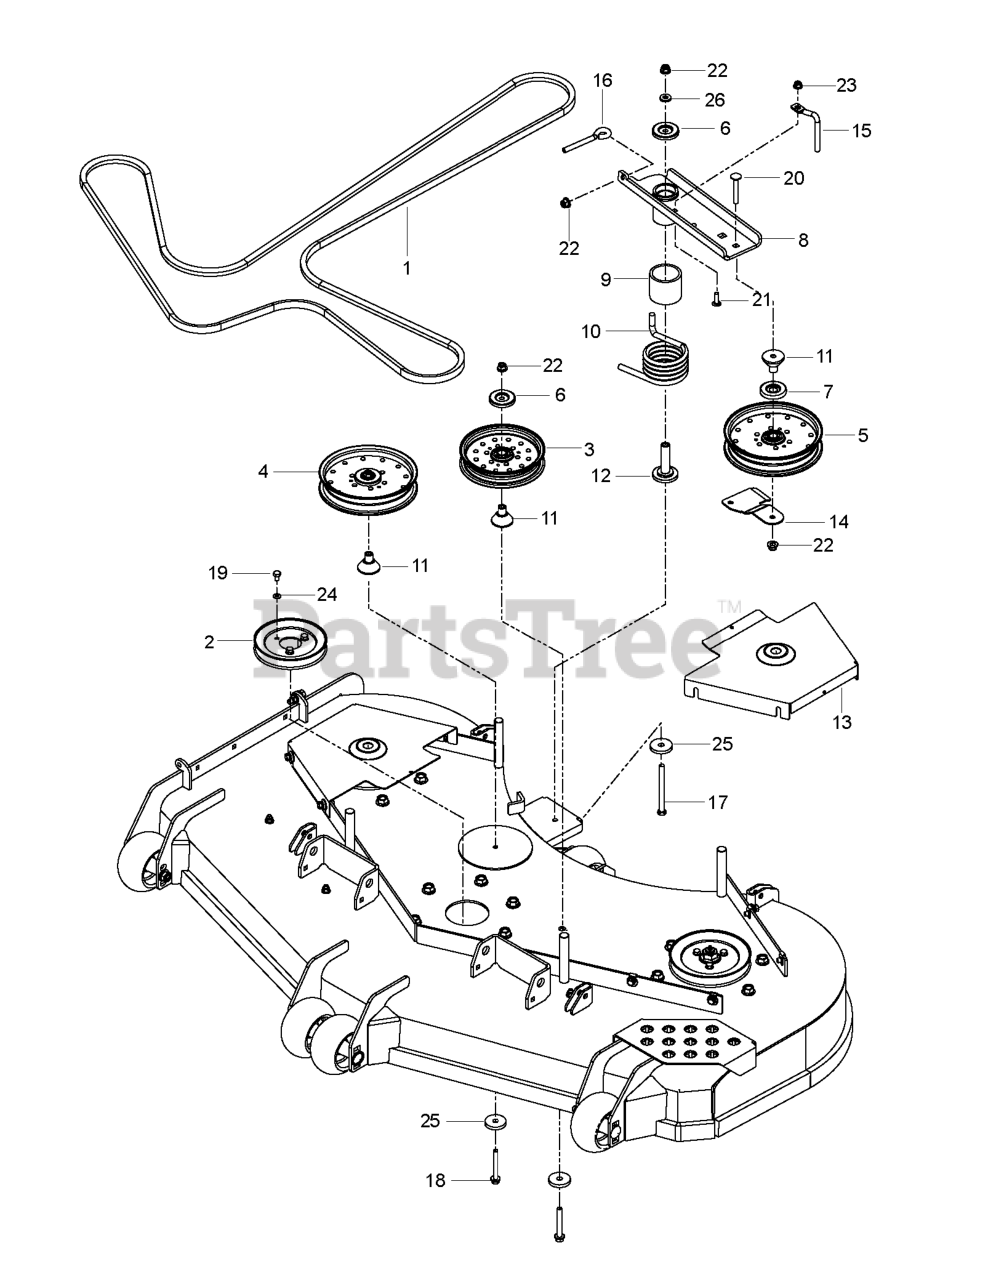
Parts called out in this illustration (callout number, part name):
1	BELT 5V 176.00
2	PULLEY - 6.57
3	PULLEY - 7" NARROW
4	PULLEY IDLER, 6" NARROW
5	PULLEY - IDLER 7"
6	DUST SHIELD
7	SHIELD, DUST
8	ASSY, IDLER ARM, PZ
9	SPACER, IDLER PIVOT
10	SPRING, TORSION, IDLER
11	BEARING, IDLER ARM
12	BEARING, IDLER PIVOT
13	SHIELD,BELT, 60" ORANGE
14	BELT.GUIDE.BLACK
15	BELT KEEPER
16	EYE BOLT, 3/8 X 4"
17	HCS 3/8-16 X 4-1/2 GR 8 ZD
18	HHFS 3/8-16 X 2-3/4 GR5 ZD
19	HCS 5/16-18 X 1/2 GR 5 ZD
20	CARRIAGE BOLT 3/8-16 X
22	NUT 3/8-16 HEX FLG NYLOC ZD
23	5/16-18 NYLOC FLANGE NUT
24	WASH 5/16 DISC SPRING ZD
25	SPINDLE WASHER
26	WASHER, 3/8 THICK
